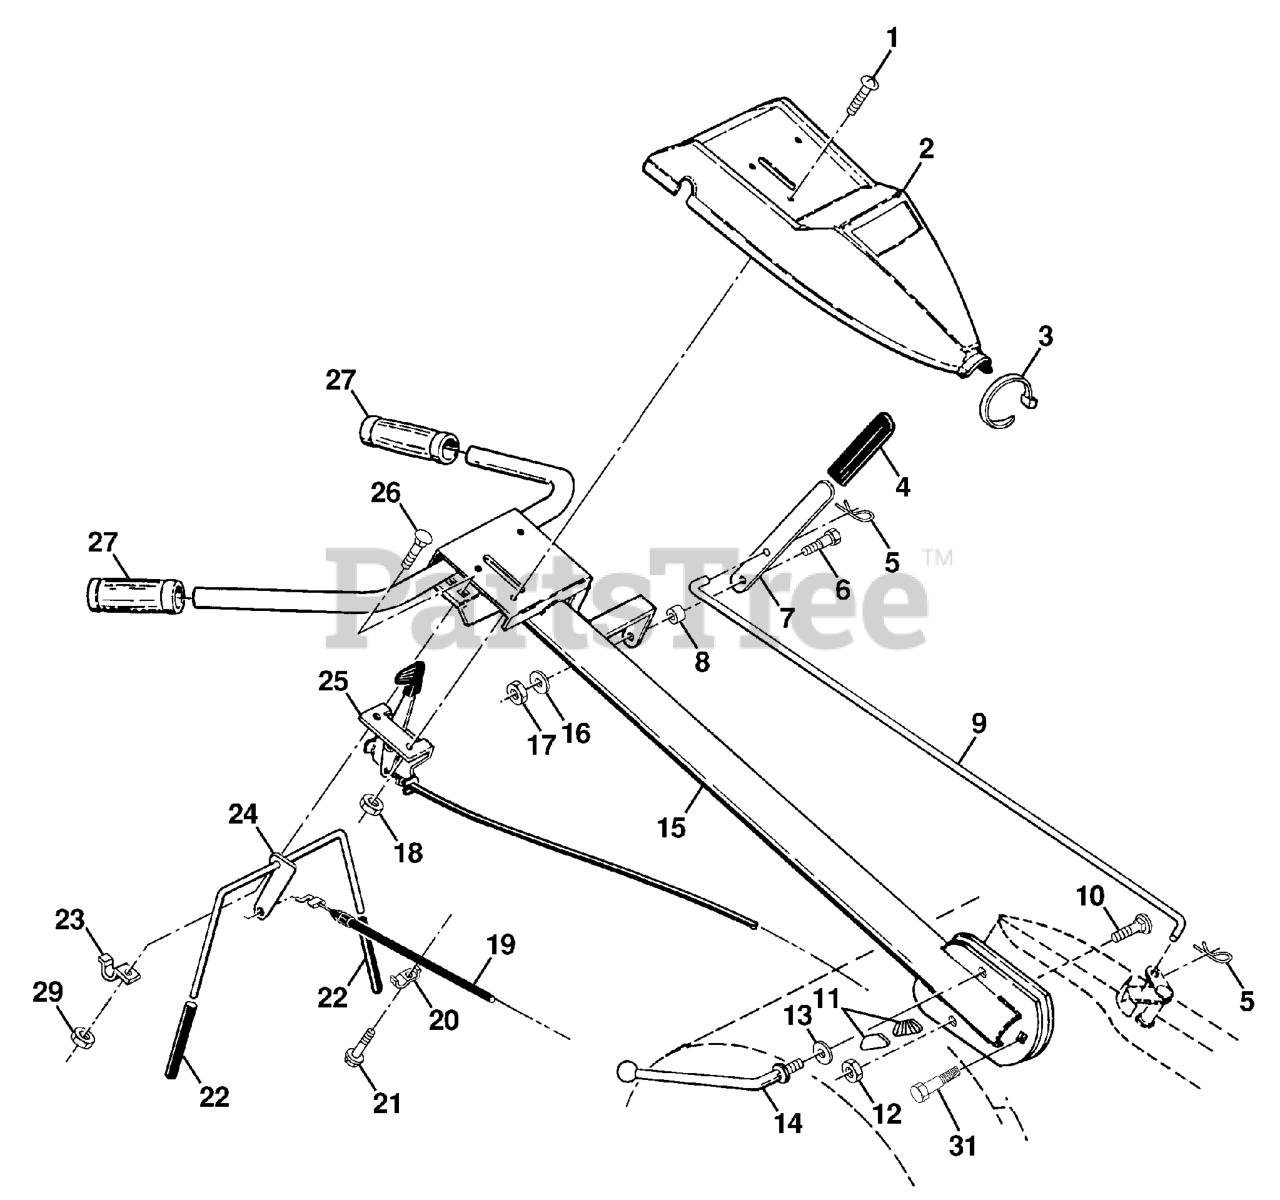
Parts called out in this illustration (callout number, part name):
1	SCREW.PNHD.10-24
3	TIE CABLE CRT
4	GRIP T
5	RETAINER M
6	SHOULDER BOLT ST
7	SHIFT HANDLE CRT
8	GROMMET.RUBBER.CRT.TILLER
9	ROD.SHIFT.YARD PRO.UNIVERSAL.
10	BOLT D
11	LOCK.HANDLE.CRT
12	LOCKNUT
13	WASHER CRT
14	LEVER.LOCK.CRT
15	HANDLE
16	LOCKWASHER
17	NUT
18	NUT **
19	CLUTCH CABLE
20	CONDUIT.CLIP.PLATED
21	TAPPING SCREW
22	GRIP BAR CRT(1)
23	CLAMP.BAR.CRT.BLACK
24	BAR ASSY CONTROL
25	THROTTLE CONTROL
26	BOLT
27	KIT.GRIP.HANDLE.5.00.BLK.VINYL
28	LOCK HANDLE
29	BOLT.PIVOT
